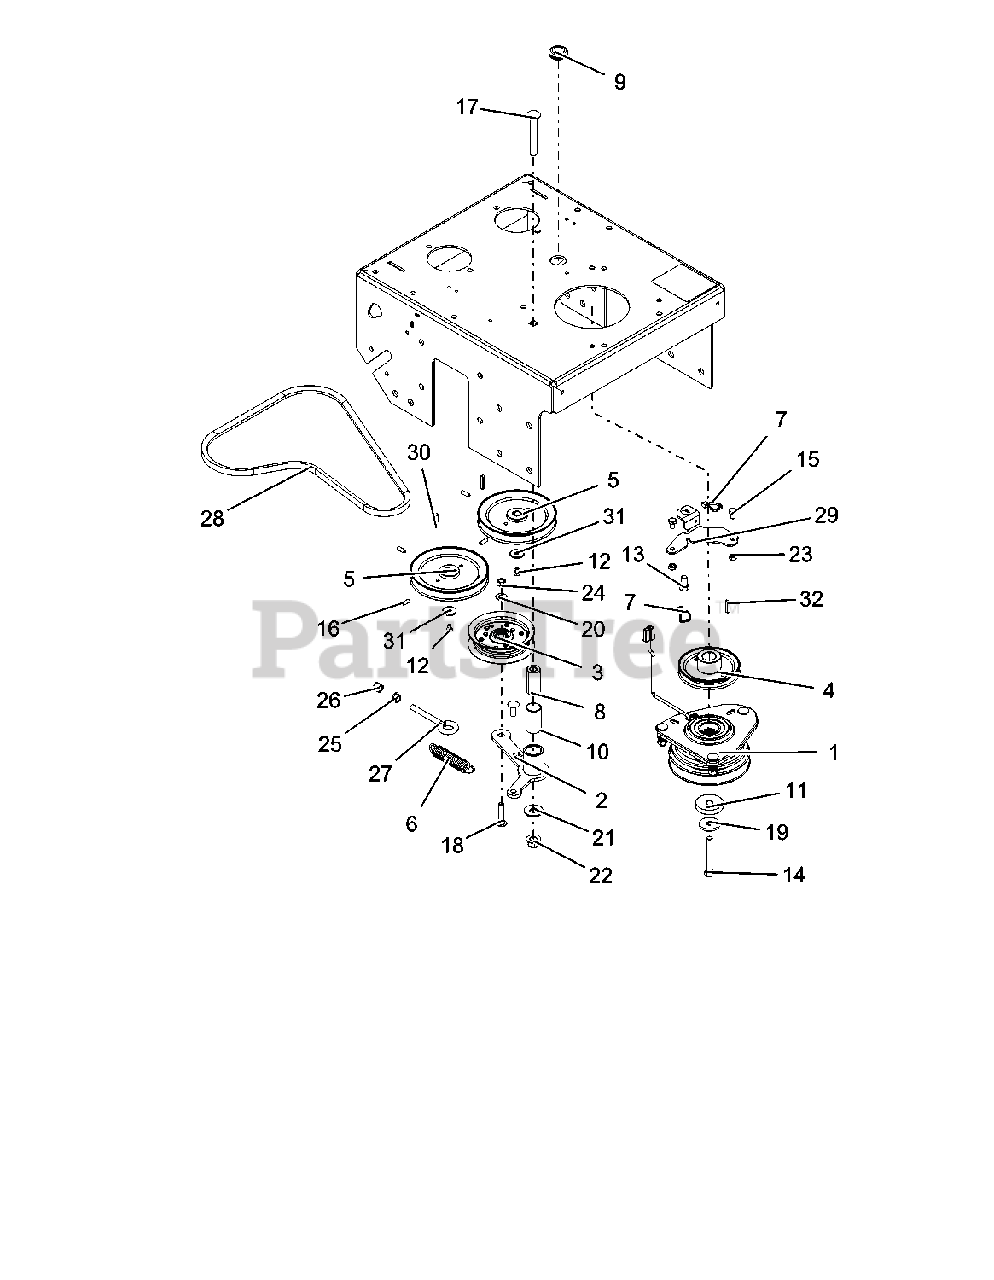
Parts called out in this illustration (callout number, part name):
1	CLUTCH ASSY, OGURA
2	WLDMT, IDLER HYD WLK TRANS
3	ASM, IDLER 4"
4	PULLEY, V-BELT WLK TRANS DRIVE
5	PULLEY, V-BELT PUMP HYD WLK
6	SPRG, EXTENSION
7	CABLE TIE, .15 X 8.50
8	BSHG, SPCR .502X.997X2.03
9	GROMMET:RUB:.88IDx1.38ODX.14GR
10	BSHG, 1.00X1.125X1.937
11	SPCR, .450 X 2.00 X .396
12	BLT-HEX M6 X 1.0X10 YWZC
13	BLT-HEX .44-14X.75 GR5 YWZC
14	BLT-HEX .44-20X3.00 GR8 YWZC NYTORQ
15	BLT-HEX .31-18X.50 GR5 YWZC
16	SCR-SET, 25-20X.75 SKHCUPDL REV
17	BLT-RHDSSQNK .50-13X3.50 G5YZ
18	BLT-RDHDSQNK .38-16X1.75 G5 YWZC
19	WSHR, 7/16" SPRING DISC
20	WSHR-FL-STL.406X.812X.065 YWZ
21	WSHR-FL-STL.563X1.38X.109YWZC
22	NUT-LK-NYL-FLG .50-13 YWZC
23	NUT-LK-CTR-JAM .31-18 YWZC
24	NUT-LK-CTR .38-16 YWZC
25	@NUT-SPNLK-FLG .375-16 YWZC
26	NUT-LK-NYL .38-16 YWZC
27	BOLT, EYE .38-16X4.50 .75 DIA
28	V-Belt, A-RAW EDGE
29	PLATE, CLUTCH DOG
30	KEY, RND - M5XM5XM30
31	WASHER, .250 WIDE HEAVY FLAT Y
32	KEY, .250 X .250 X .995 TPR
